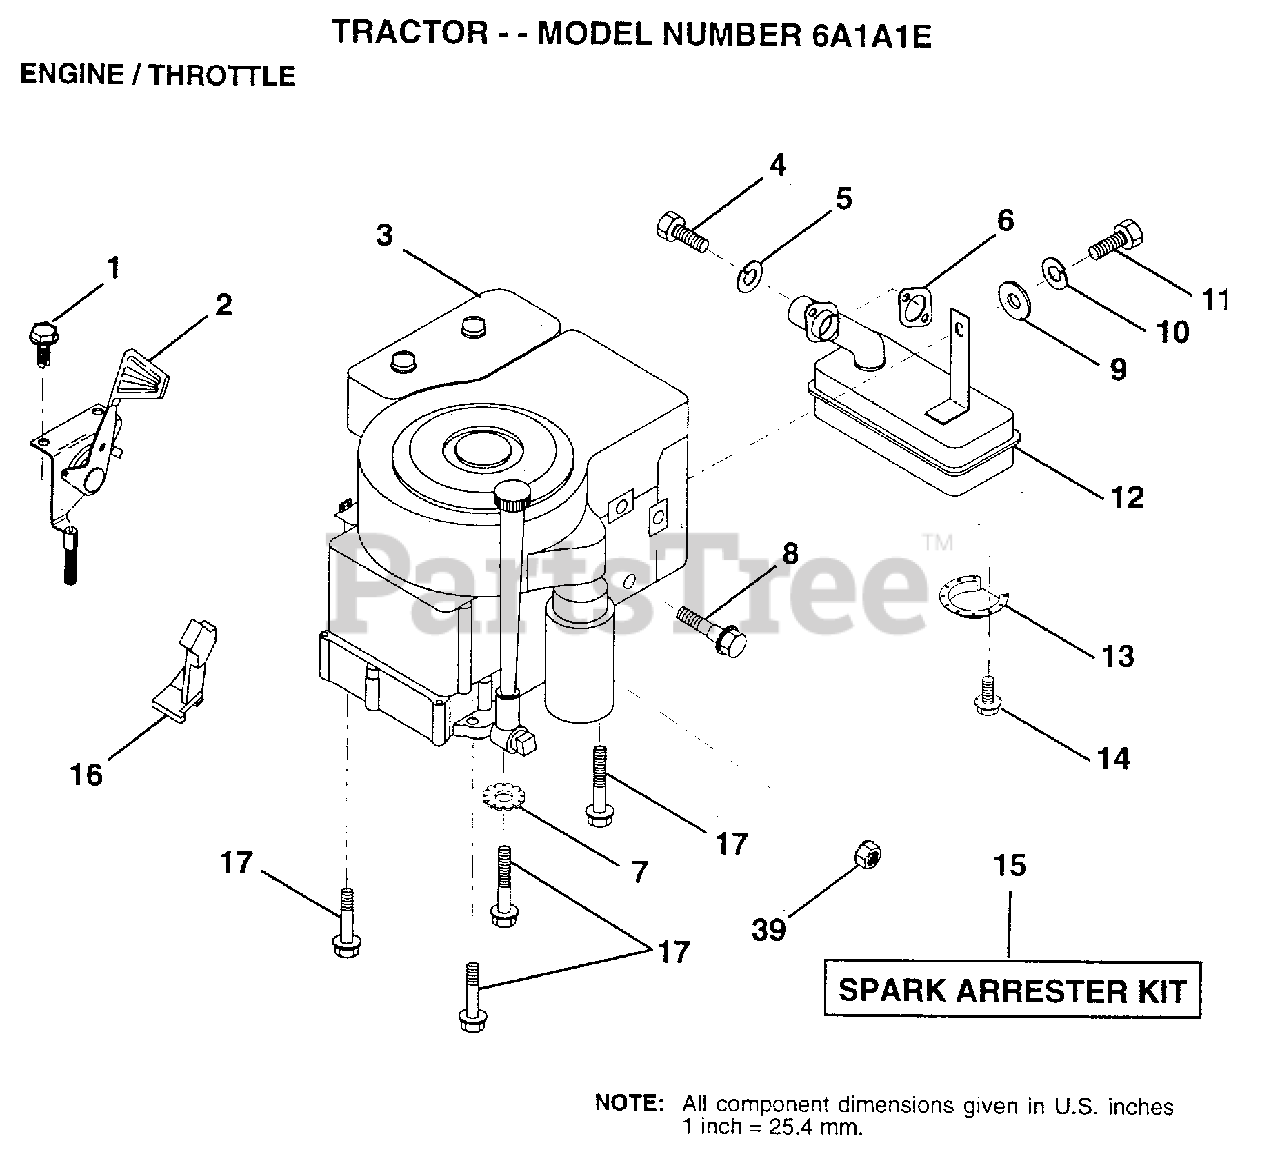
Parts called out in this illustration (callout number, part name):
1	SCREW.1/4-20X1/2
4	SCREW
5	LOCKWASHER
6	GASKET ENG 1 313 LD TIN PLATED
7	LOCKWASHER
8	BOLT T
10	LOCKWASHER
12	MUFFLER
13	DEFLECTOR.222573
16	"STOP,DASH THROTT"
17	SCREW LT
39	NUT
